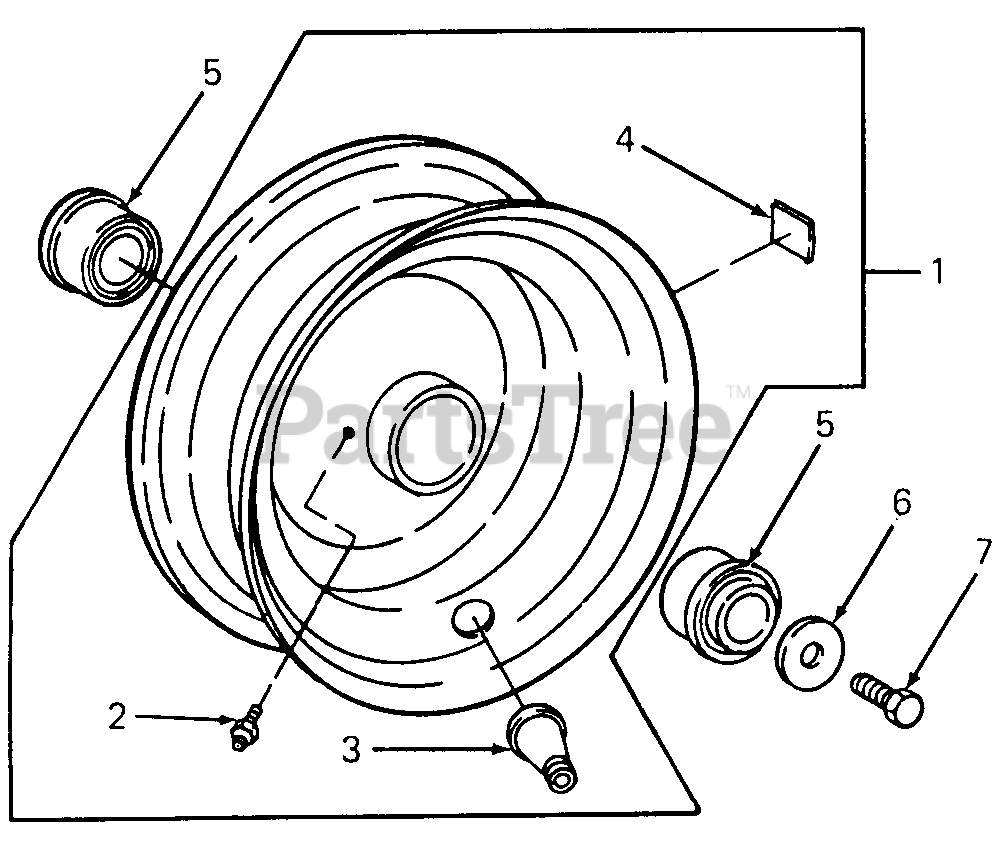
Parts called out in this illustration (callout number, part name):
1	Wheel Assy, Front
2	Fitting, Lube
3	Valve, Tubeless Air
4	Label, Inflation
5	Bearing, Wheel Ball
6	Washer, Flat, .406 X 1.75 X .105 Thk
7	Screw, Hex Cap, 3/8-16 X .75 Lg GR5
